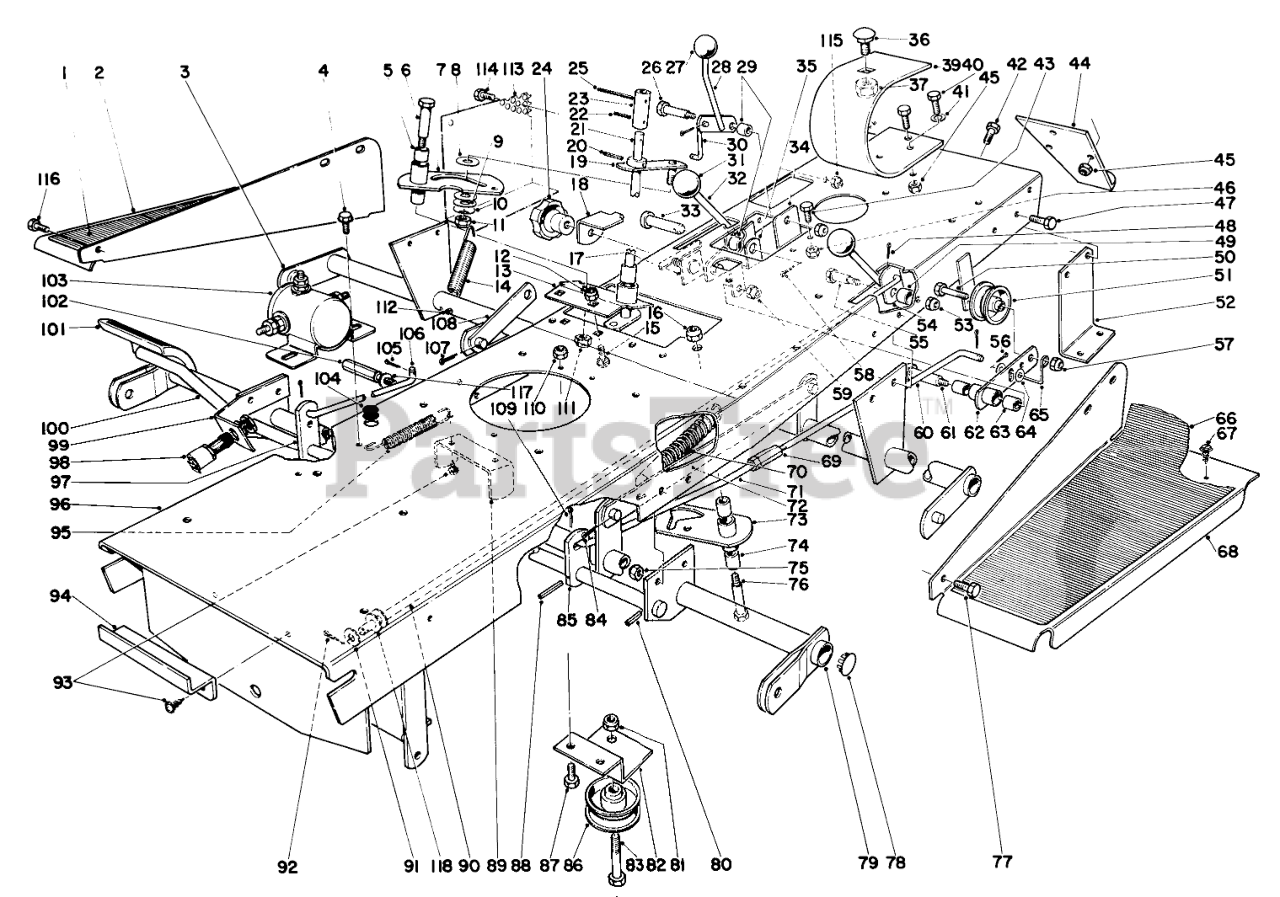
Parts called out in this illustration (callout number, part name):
1	Pad R. H.
2	Footrest R.H.
3	Cross Tube Rear
5	Bushing
6	Shoulder Bolt
7	Cam Plate
8	Washer
9	WASHER-FLAT
10	Spring Washer
12	Nut
13	Bracket-Control
14	Spring Tension Traction Clutch
15	BOLT-CARR
17	Knob Plate
18	Slide
19	Control Crank
20	PIN-SPRING
21	Handle Hydro Control
22	PIN-SPRING
23	Sleeve Handle
25	Roll Pin
26	Shoulder Bolt
27	Knob
28	Handle Traction
29	Spacer
30	Link Traction Clutch
32	Lever
34	Bracket Traction Clutch
35	Support Height of Cut Lever
36	SCREW-CARR
39	Seat Spring
40	SCREW-HH
41	WASHER-LOCK
42	SCREW-HH
43	SCREW-HH
44	Hitch
47	SCREW-HH
48	PIN-COTTER
49	Spacer
50	SCREW-HH
51	Pulley
52	Axle Support L.H.
54	Lever
55	Shoulder Bolt
56	PIN-COTTER
58	PIN-COTTER
60	Brake Rod Rear
61	Shoulder Bolt
62	Arm Traction Idler Incl. Ref. #63
63	Bushing
64	WASHER-FLAT
65	Guide Belt Rear
66	Pad Left
67	10-16 X 3/8 THDG SCREW
68	Footrest
69	Screw Brake Adjusting
70	Spring Counterbalance
71	Brake Rod Front
72	Lift Equalizer
73	Plate Neutralizer
74	Bushing
75	Nut
76	Shoulder Bolt
77	SCREW-HH
78	Plug Button
79	Cross Tube Front
80	PIN-SPRING
81	Locknut
82	Bracket Fixed Idler
83	SCREW-HH
84	PIN-COTTER
85	Lever Brake
86	Pulley
87	SCREW-HH
88	PIN-ROLL
89	Cutter Guide
90	Rod Clutch
91	WASHER-FLAT
92	PIN-COTTER
93	10-32 X 1/2 PHILLIPS
94	Spring Clip
95	Spring
96	Frame Hydrostatic
97	Pedal Crank Neutralizer
98	Switch
99	Bracket Switch
100	Pedal
101	PAD-BRAKE
102	Brake Stop
103	Solenoid
104	GROMMET
105	PIN-COTTER
106	Link Neutralizer
107	PIN-COTTER
108	Lift Link
109	PIN-COTTER
110	Nut
112	PIN-ROLL
113	Fan Guide Side
114	SCREW-HH
115	NUT-LOCK, CONE
116	SCREW-HH
117	WASHER-FLAT
118	GRILLE HINGE SPACER
